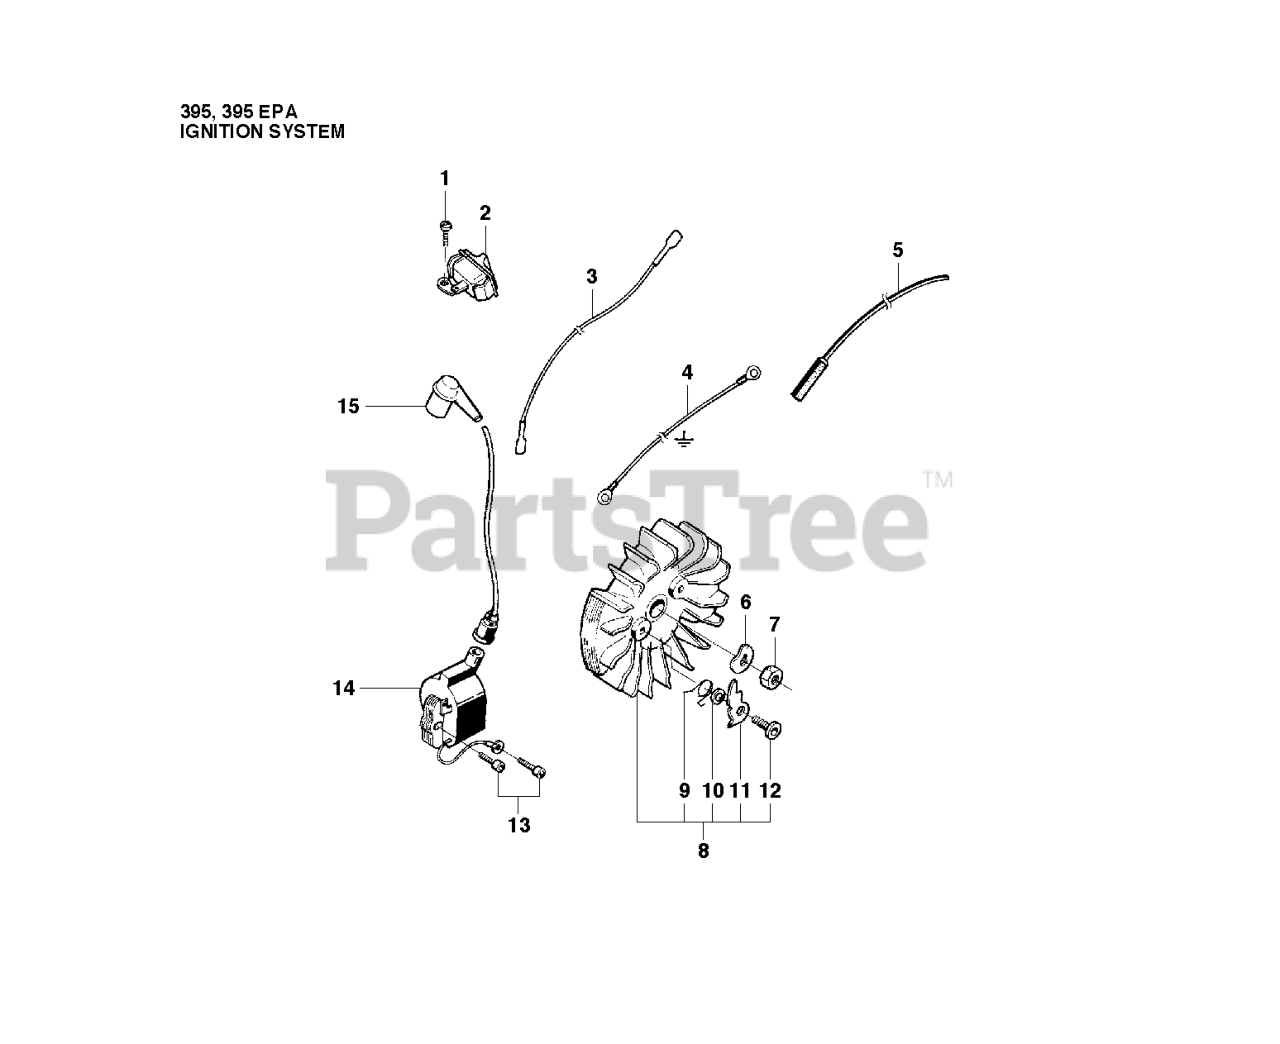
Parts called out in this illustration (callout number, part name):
2	SWITCH ON/OFF
5	REPAIR CABLE
6	WASHER 8.4X16
12	SCREW M5X14
13	SCREW MC6S 4X20
14	IGNITION COIL
15	SPARK PLUG CONN. KIT
